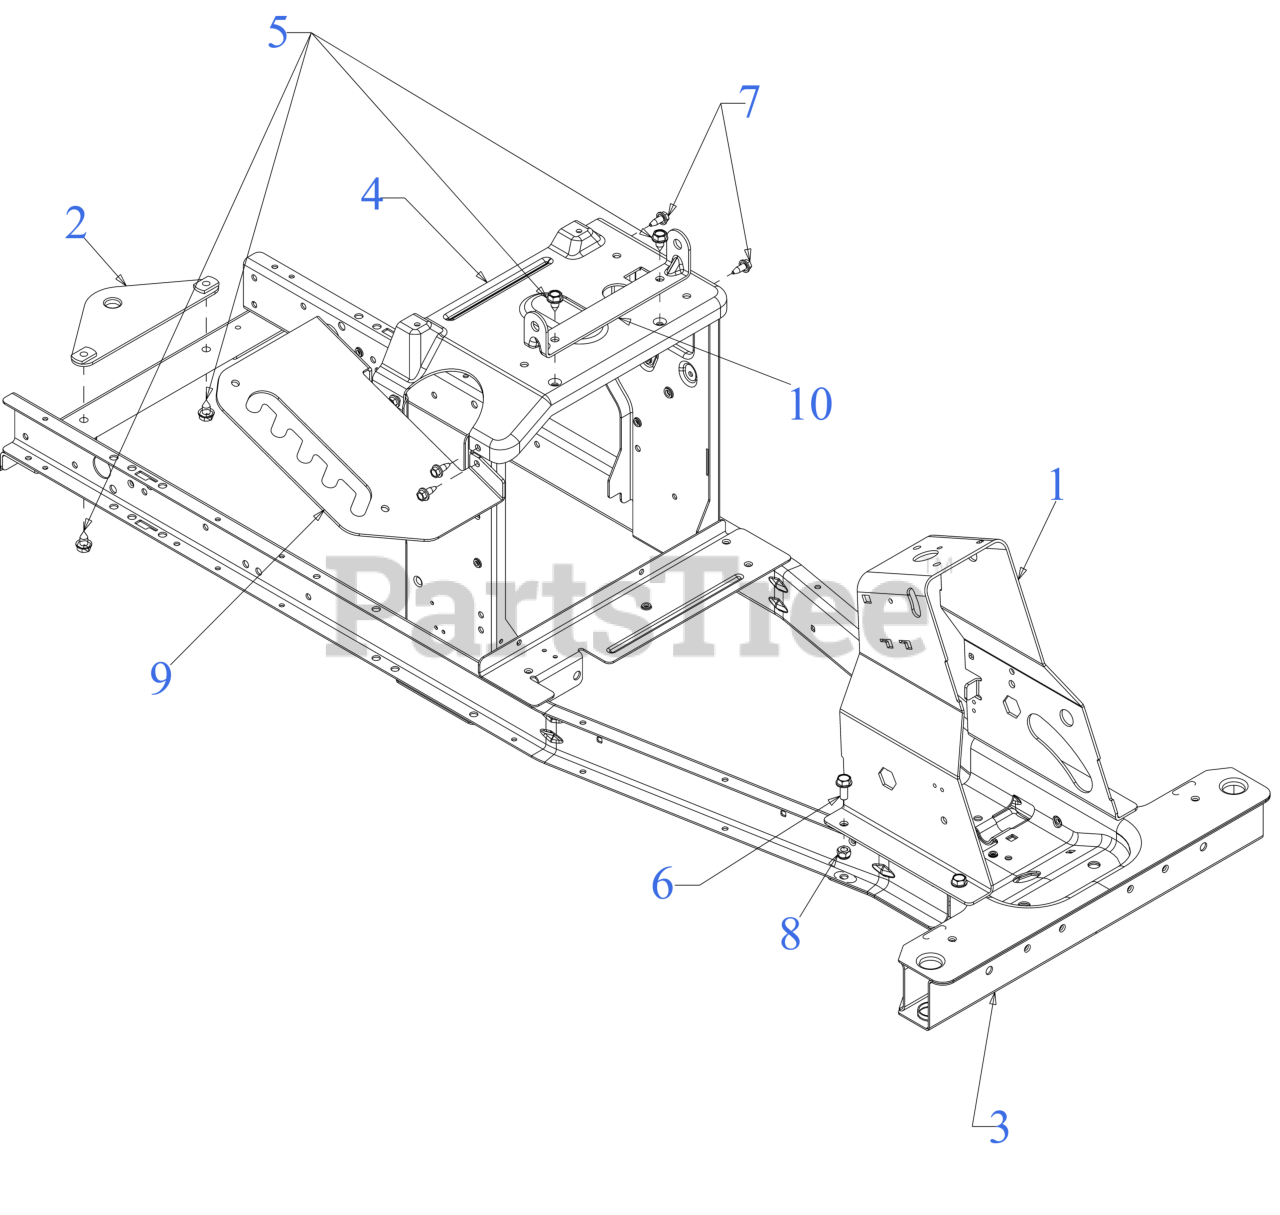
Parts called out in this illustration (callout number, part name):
1	STEERING PEDESTAL
3	FRAME ASSEMBLY
4	PAN:SEAT:ASM:EL
5	SCREW 5/16-18 x .625
6	SCREW 5/16-18 x .750 GR8
7	SCREW 1/4-20X.625
8	HEX NUT
9	DECK LIFT INDEX BRACKET
10	SEAT PIVOT BRACKET
